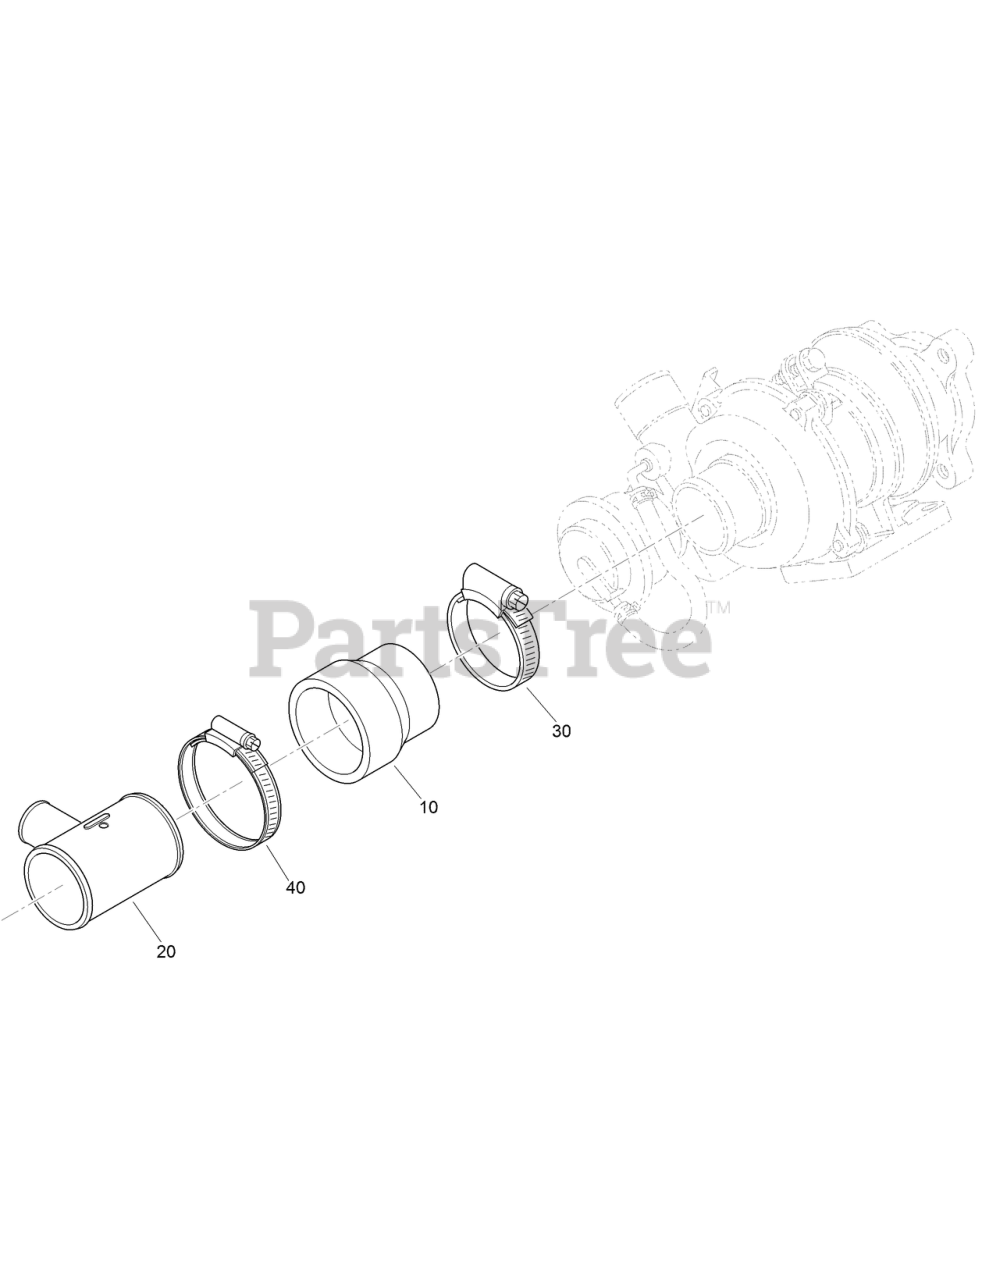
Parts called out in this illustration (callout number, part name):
10	TUBE-INLET, TURBO
20	PIPE-BREATHER
40	CLAMP-HOSE
